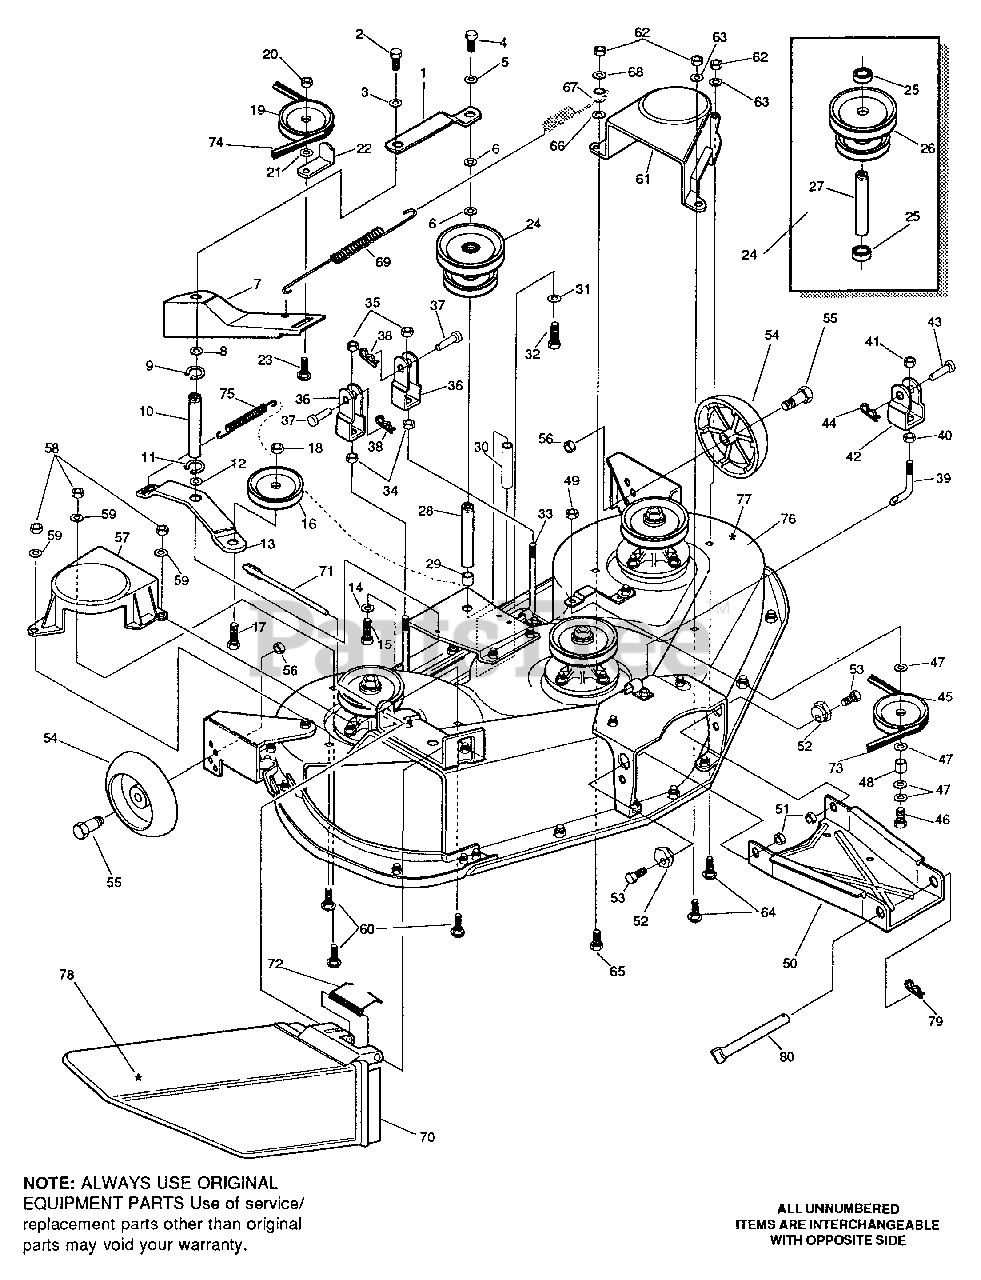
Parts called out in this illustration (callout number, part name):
1	Bracket, Jackshaft
2	Screw, 5/16-24 x .88 HHC
3	Washer, Splitlock, .328 x .60 x .11
4	Screw, 3/8-24 x 1.00 Nylon
5	Washer, Splitlock
6	Washer, .391 x 2.25D x .07
7	Bracket, Idler
8	Washer, Flat .640 x 1.25 x .06
9	Ring, Retaining
10	Idler Shaft
11	Ring, Retaining
12	Washer, Flat .640 x 1.25 x .06
13	Bracket, Idler
14	Washer, Splitlock, .328 x .60 x .11
15	Screw, 5/16-24 x .88
16	Pulley, Idler
17	Screw, 3/8-16 x 1-3/4 In.
18	Nut, 3/8-16 Centerlock
19	Pulley, Idler
20	Nut, Hex, Ctrlk, 3/8-16 Thd.
21	Washer, Flat .391 x 1.00 x .125
22	Belt Retainer
23	Bolt, 3/8-16 x 2.00 Carriage
24	Shaft, Assy. Jack
25	Bearing, Ball
26	Pulley, Assy.
27	Spacer Tube
28	Jackshaft
29	Spacer Tubing, 46" Deck
30	Spacer Tube 46" Deck
31	Washer, Splitlock, .393 x .68 x .10
32	Screw, 3/8-24 x 1 In.
33	Rod, Lift 46" Deck Long
34	Nut, 1/2-13 Hex Jam
35	Nut, 1/2-13 Square
37	Clevis Pin
38	Hair Pin
39	Rod, Lift Front Short
40	Nut, 1/2-13 Jam
41	Nut, 1/2-13 Square
43	Clevis Pin
44	Hair Pin
45	Idler Pulley
46	Screw, 3/8-16 x 2.50
47	Washer, Flat
49	Nut, 3/8-16 Centerlock
50	Channel Drawbar
51	Nut, 5/16-18 Centerlock
52	Adjusting Nut
53	Screw, 5/16-18 x 1.00 In.
55	Shoulder Bolt, 3/8-16
56	Nut, 3/8-16 Centerlock
57	Guard, Belt R.H.
58	Nut, 1/4-20 Centerlock
59	Washer, Flat
60	Carriage Bolt, 1/4-20 x 5/8 In.
61	Cover, Belt LH
62	Nut, 1/4-20 Centerlock
63	Washer, Flat
64	Carriage Bolt, 1/4-20 x 5/8 In.
65	Screw, 1/4-20 x 1.25 HHC
66	Washer, Flat
68	Flatwasher
71	Rod, Pivot
72	Torsion Spring
73	Belt, V 4L
74	Belt, V 5L 63.70
75	Tension Spring
76	Deck, Mower Assy.
77	Decal, No Step
78	Decal, Cut Hand
79	Hair Pin
80	Rod, Draw Bar
